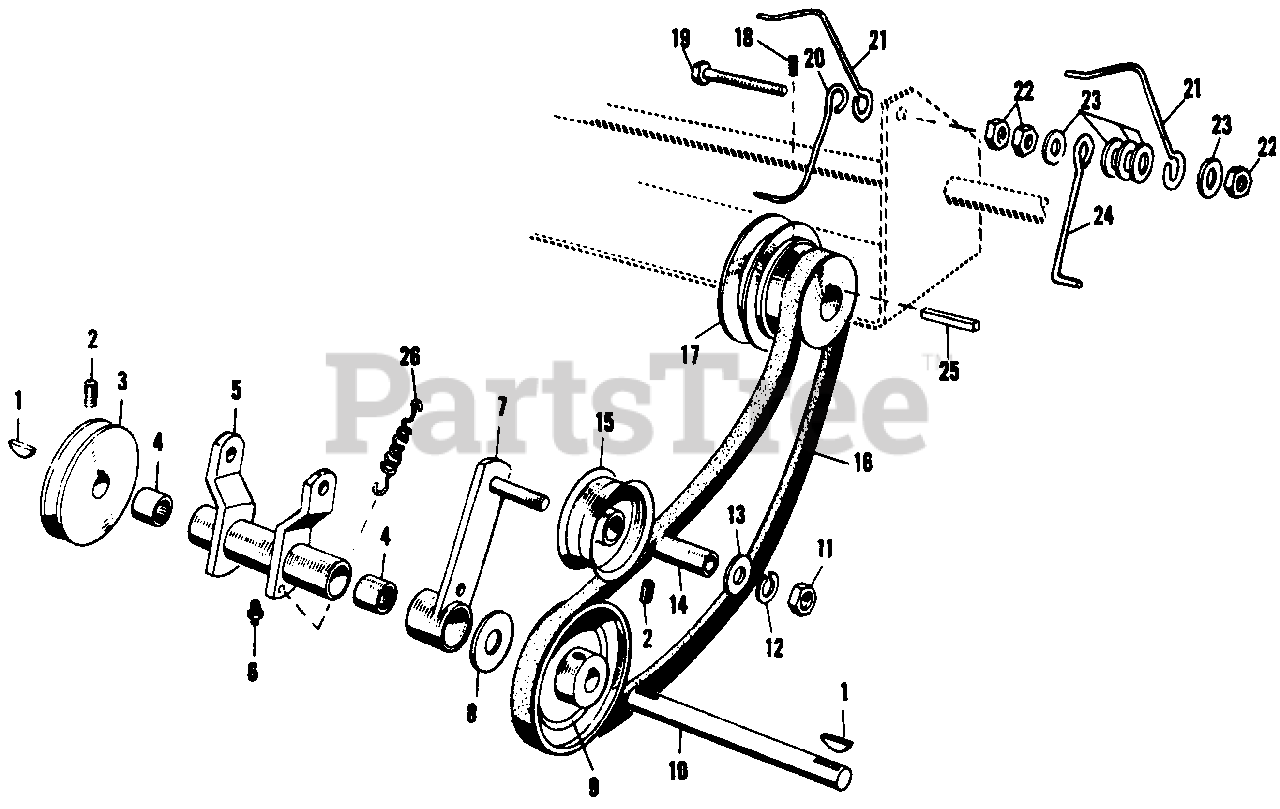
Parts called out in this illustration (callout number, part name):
4	Bearing, Needle
5	Bracket Assembly, Drive
7	Lever, Idler Assembly
10	Shaft, Idler
14	Race, Inner Bearing
15	Pulley, Idler
16	V-Belt, 34" long
17	Pulley, Engine
20	Stop, Belt
21	Stop, Belt
24	Stop, Belt
25	Key, Engine
